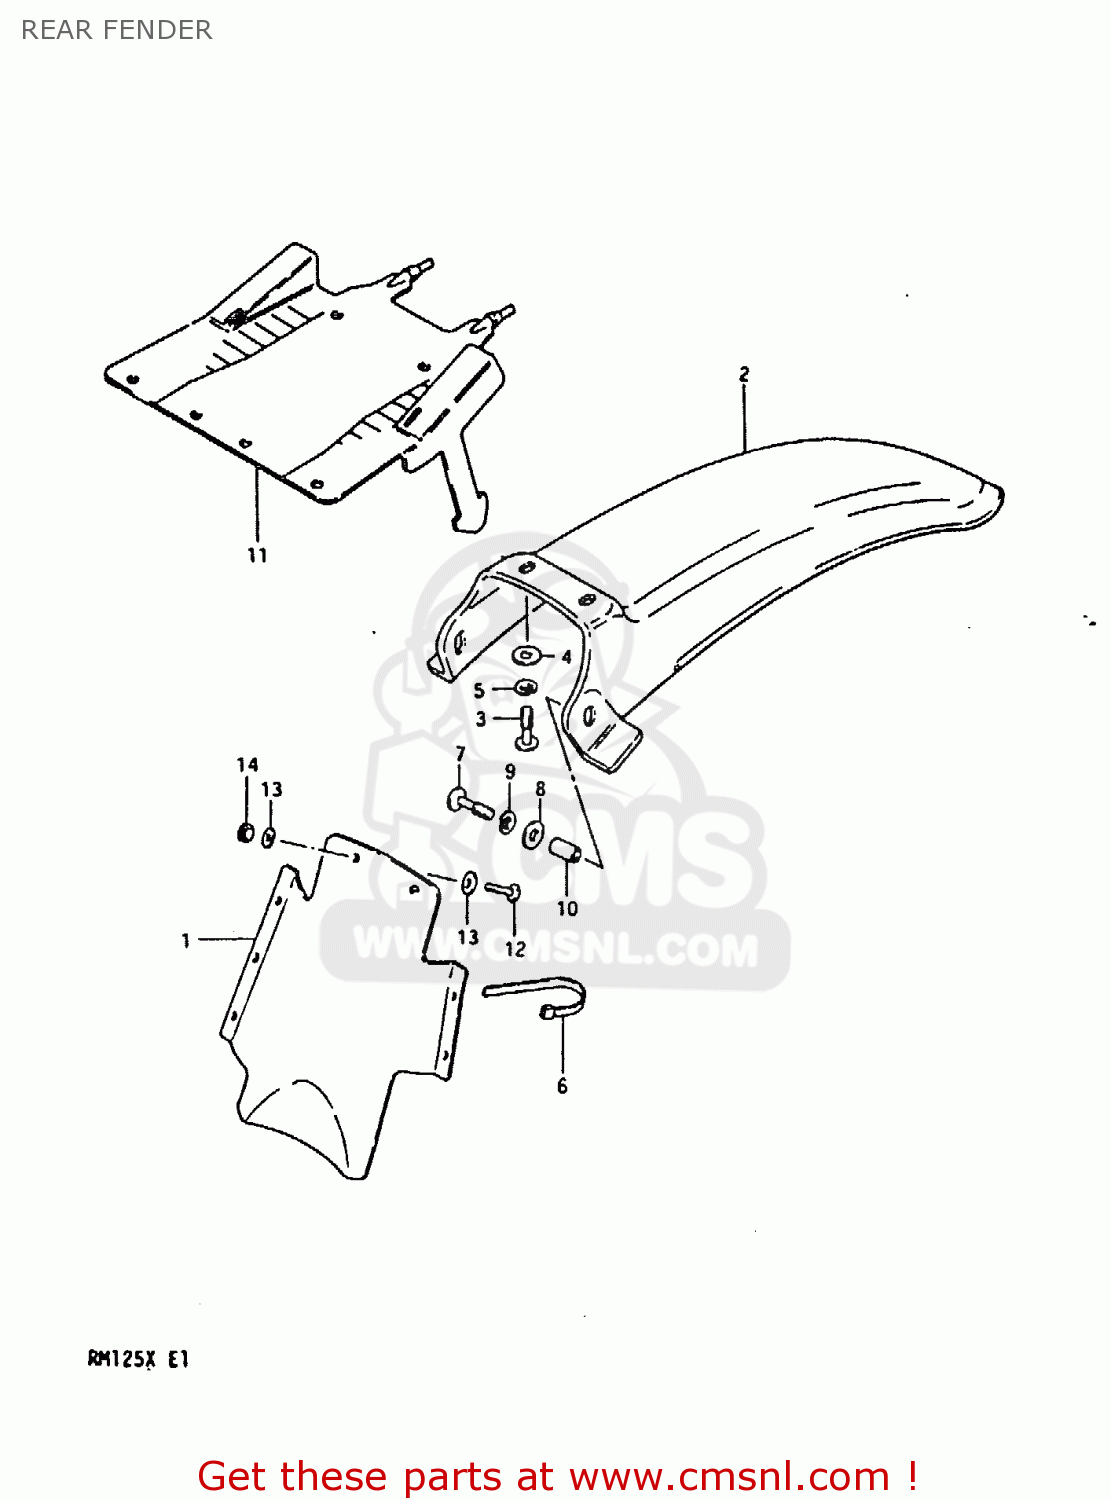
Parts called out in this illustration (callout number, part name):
1	FENDER,REAR
2	FENDER,REAR
3	SCREW
4	WASHER (6.5X20X1.2)
5	LOCK WASHER
6	CLAMP
7	SCREW
8	WASHER (6.5X20X1.2)
9	LOCK WASHER
10	SPACER
11	GUIDE,RR FENDER MUD
12	SCREW
13	WASHER
14	NUT
